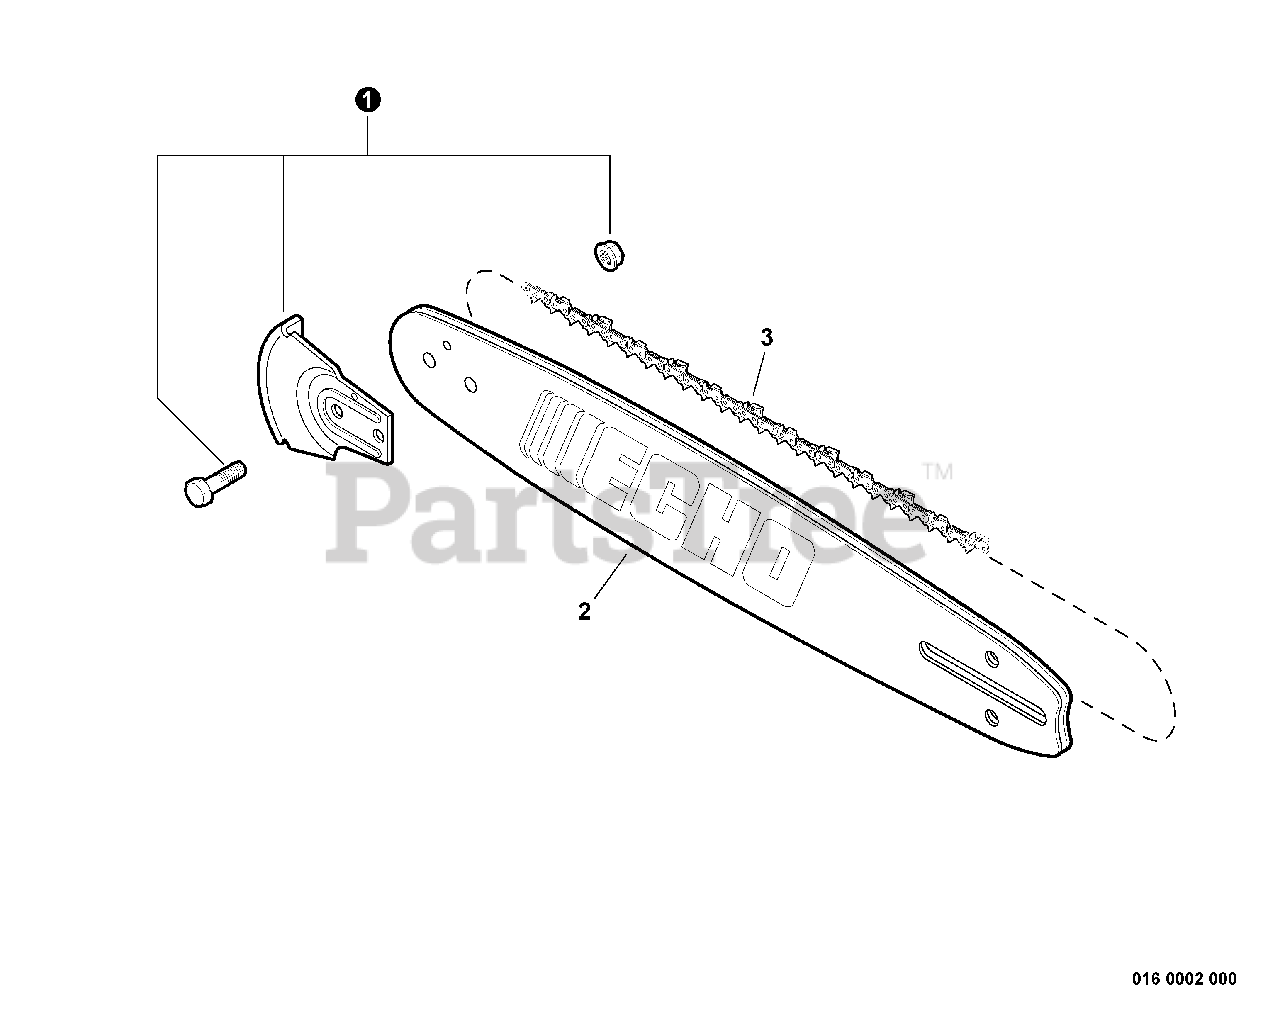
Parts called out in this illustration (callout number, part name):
1	KICK GUARD KIT
2	GUIDE BAR, 16" PRO 91
3	SAW CHAIN 16"
